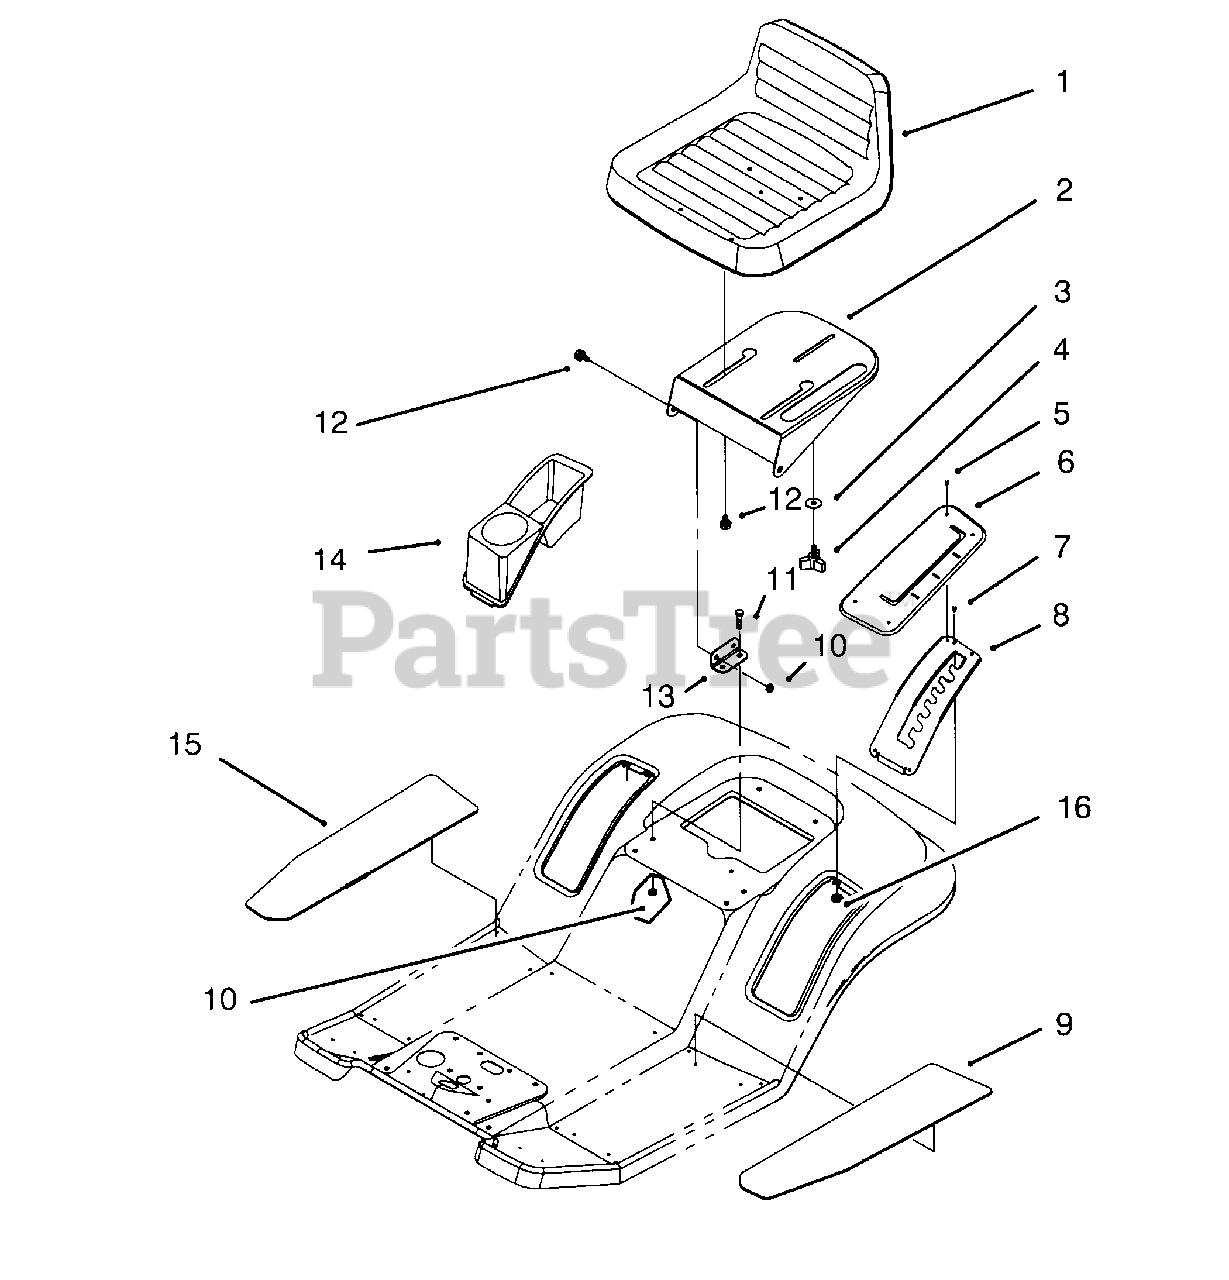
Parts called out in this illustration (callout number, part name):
1	Seat
2	Support-Seat
3	Washer-Fender
4	Knob-Studded
5	Panel-Fastener
6	Cover-H.O.C.
7	Rivet-Pop
8	Gate-H.O.C.
9	Tread-L.H. Foot
10	Nut-Lock
11	Screw-Hex Hd. Cap
12	Bolt-Shoulder
13	Bracket-Seat Hinge
14	Tray-Fender
15	Tread-R.H. Foot Hydro
16	Washer-Backup
